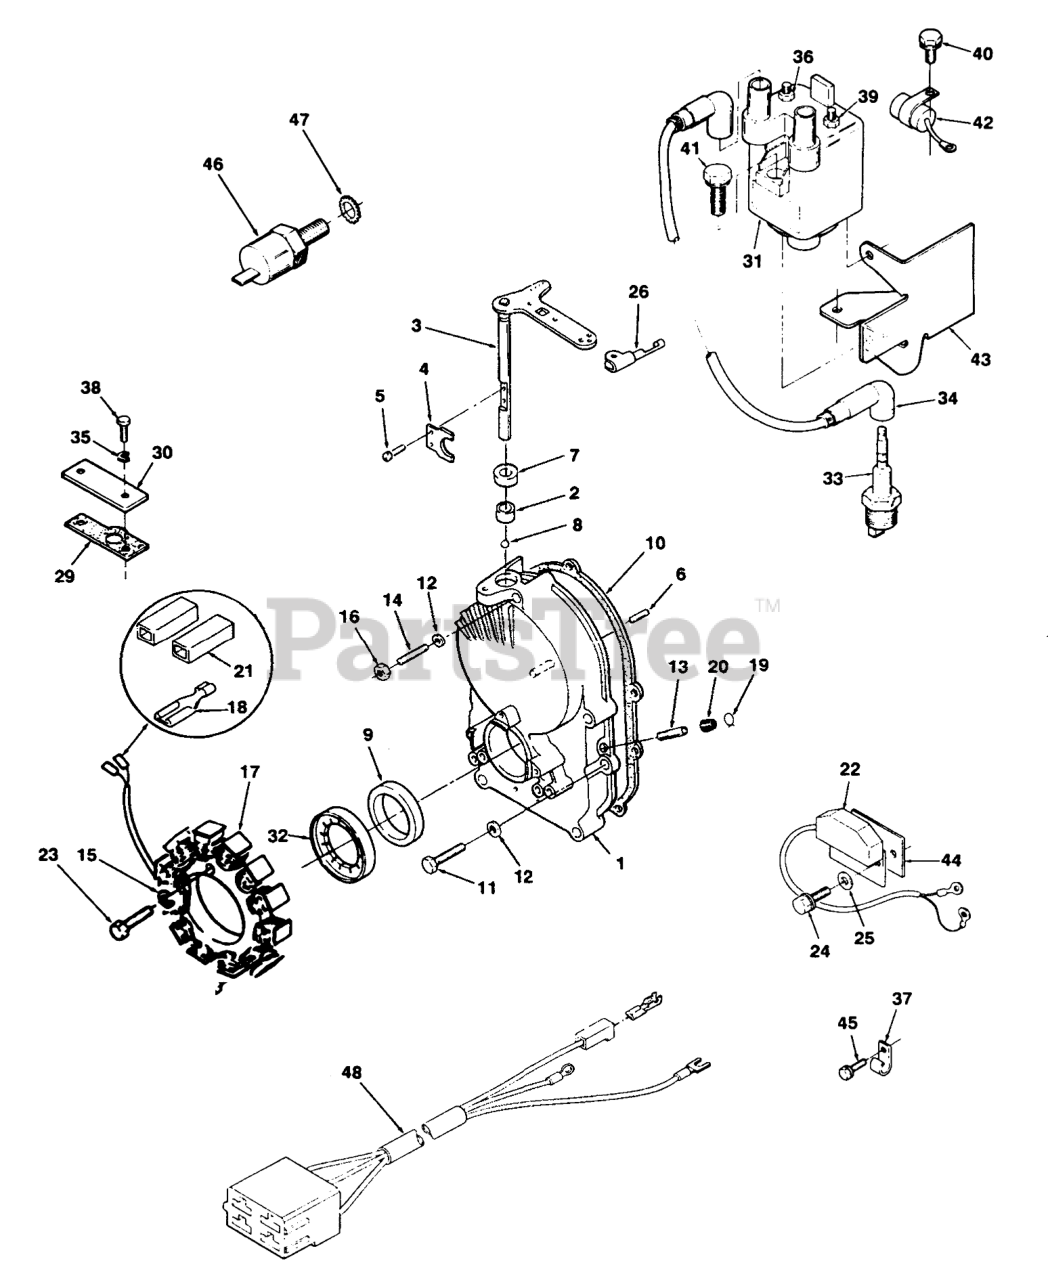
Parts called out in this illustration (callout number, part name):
1	Kit-Gearcase (Incl. Ref.#2 thru 9)
2	BEARING
3	Governor Shaft & Arm Chromed
5	SCREW-PAN HD
6	PIN-DOWEL
10	Gasket
11	Bolt
12	WASHER
13	TUBE-PORT, VACUUM
14	STUD-GEAR COVER
15	Washer-Lock
16	NUT-GEAR COVER
17	Stator
18	TERMINAL
19	CLAMP
20	CAP-FUEL OUTLET
21	BODY-TERM. CONNECTOR KIT
22	CONTROL-IGNITION
23	Screw-HH
24	Bolt
25	WASHER-LOCK
29	Gasket-Plate
30	PLATE-COVER
31	COIL-BATTERY IGNITION
32	ROTOR-IGNITION
33	SPARK PLUG
34	Wire-Plug
35	WASHER-FLAT
36	Nut
37	CLIP-WIRE
38	SCREW - CAP HEX HEAD
39	Nut
40	HEX HD CAPSCREW
41	Bolt
42	CONDENSER
43	BRACKET - COIL MTG
44	Insulator
45	Bolt
46	HIGH TEMPERATURE
47	WASHER-LOCK EXT TO
48	WIRE HARNESS
